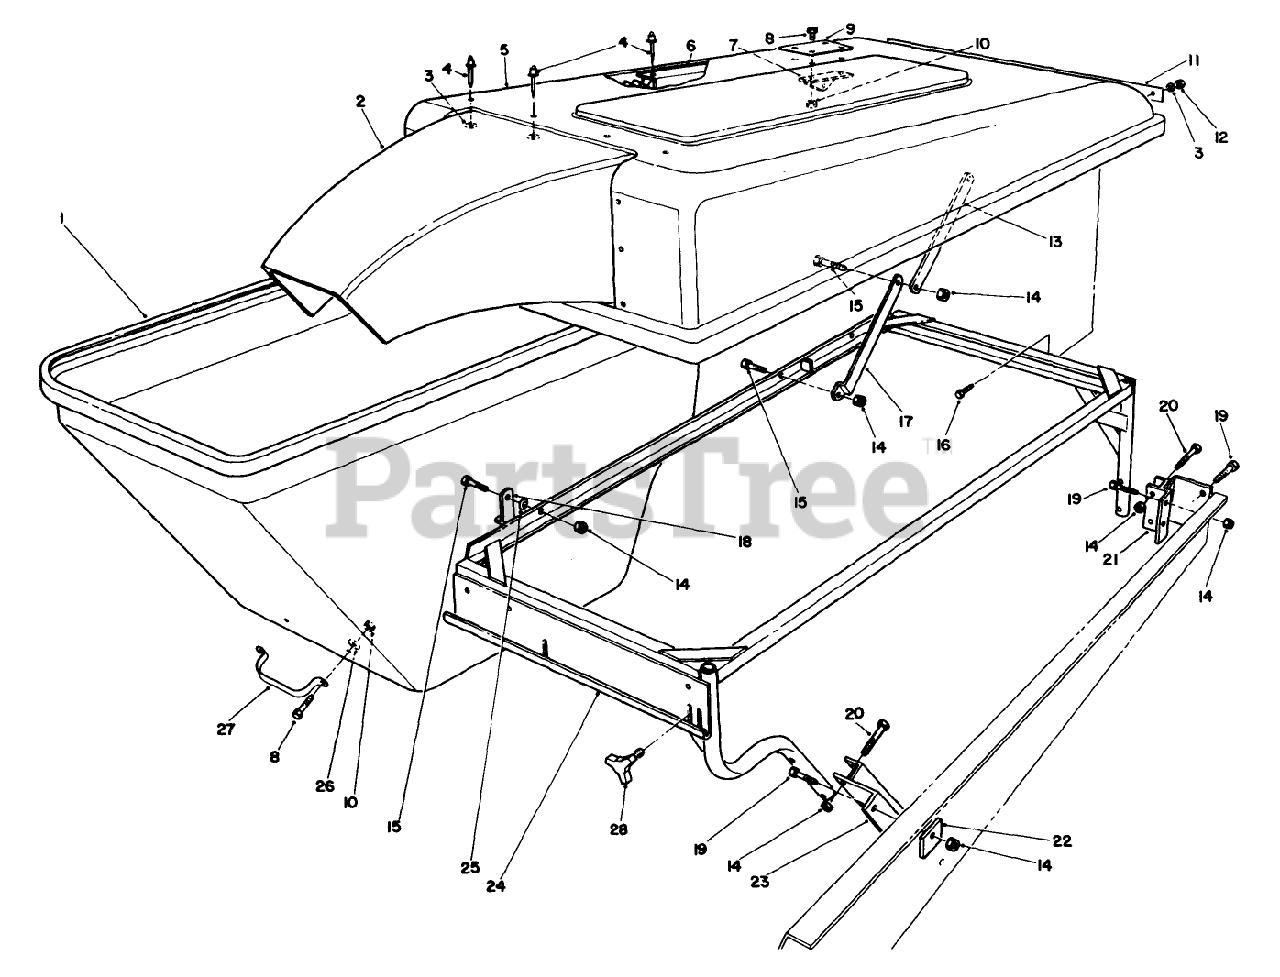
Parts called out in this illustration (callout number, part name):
1	BAGGER HOPPER
2	BAGGER SNOUT
3	WASHER-FLAT
4	RIVET-POP
5	Hood-Bagger
6	Bagger Screen
7	Pivot
8	SCREW-HH
9	HOOD PLATE
10	NUT-LOCK, NI
11	HINGE PLATE
12	NUT-LOCK, NI
13	Link
14	NUT-LOCK, NI
15	SCREW-HH
17	Link-Bag
18	Latch-Hopper
19	SCREW-HH
20	SCREW-HH
21	Bracket-Rear
22	Plate-Reinforcing
23	Bracket-Front
24	HOPPER FRAME WA
25	WASHER-SPRING
26	WASHER-FLAT
27	Handle
